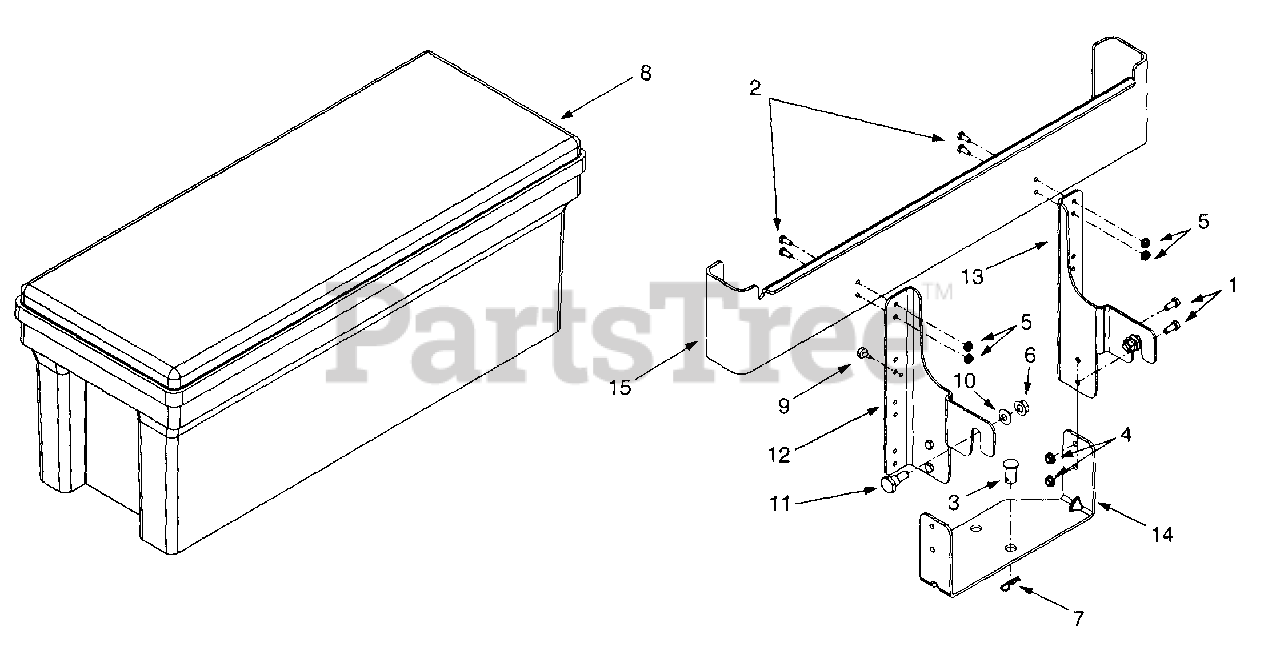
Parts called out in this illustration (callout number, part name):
1	Hex Cap Screw, 5/16-18 x .75
2	Hex Cap Screw, 1/4-20 x .62
3	Clevis Pin
4	Hex Flange Lock Nut, 5/16-18
5	Hex Flange Lock Nut, 1/4-20
6	Hex Flange Lock Nut, 7/16-20
7	Internal Cotter Pin, .148 x 3
8	Plastic Tool Box
9	Bumper, .62 Dia. x .3
10	Bell Washer, .45 x 1.0 x .062
11	Shoulder Screw, .625 x .5, 7/16-20
12	RH Support Bracket
13	LH Support Bracket
14	Cross Support Bracket
